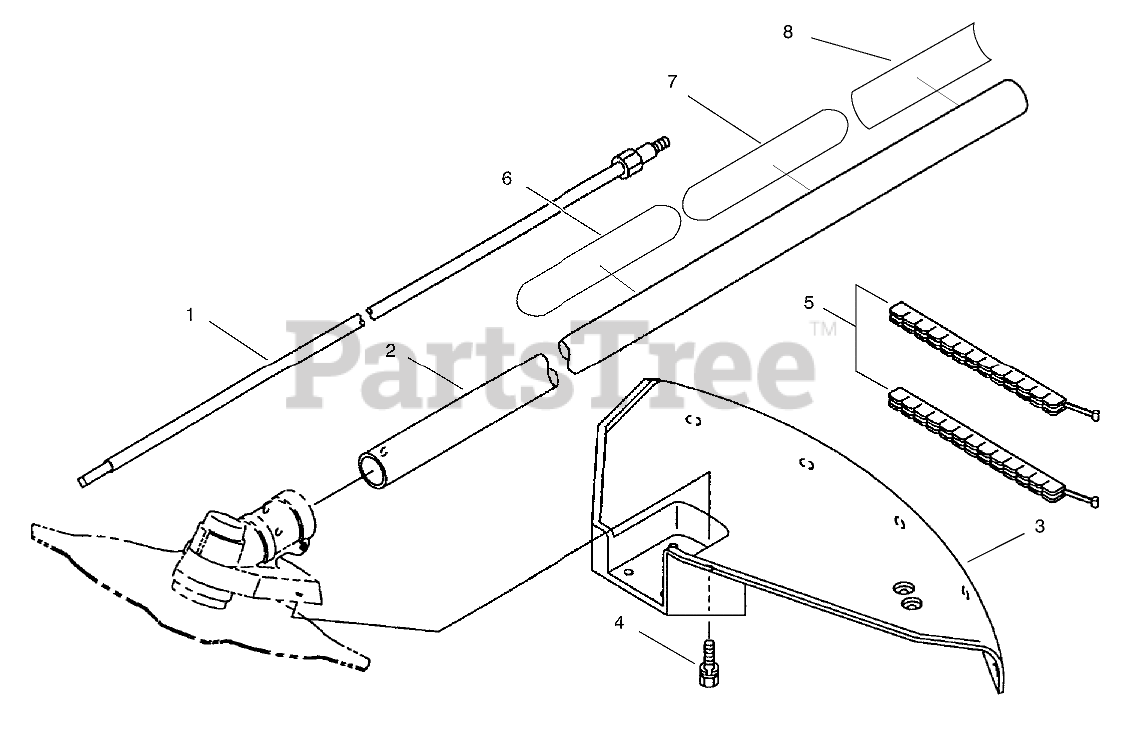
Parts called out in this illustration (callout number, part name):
1	ASM - DRIVESHAFT
2	Driveshaft Tube Assembly (Incl. Ref. # 6, 7)
3	COVER - SAFETY
5	COVER - BLADE
6	DECAL - CAUTION
7	DECAL - CAUTION
8	DECAL - TORO
